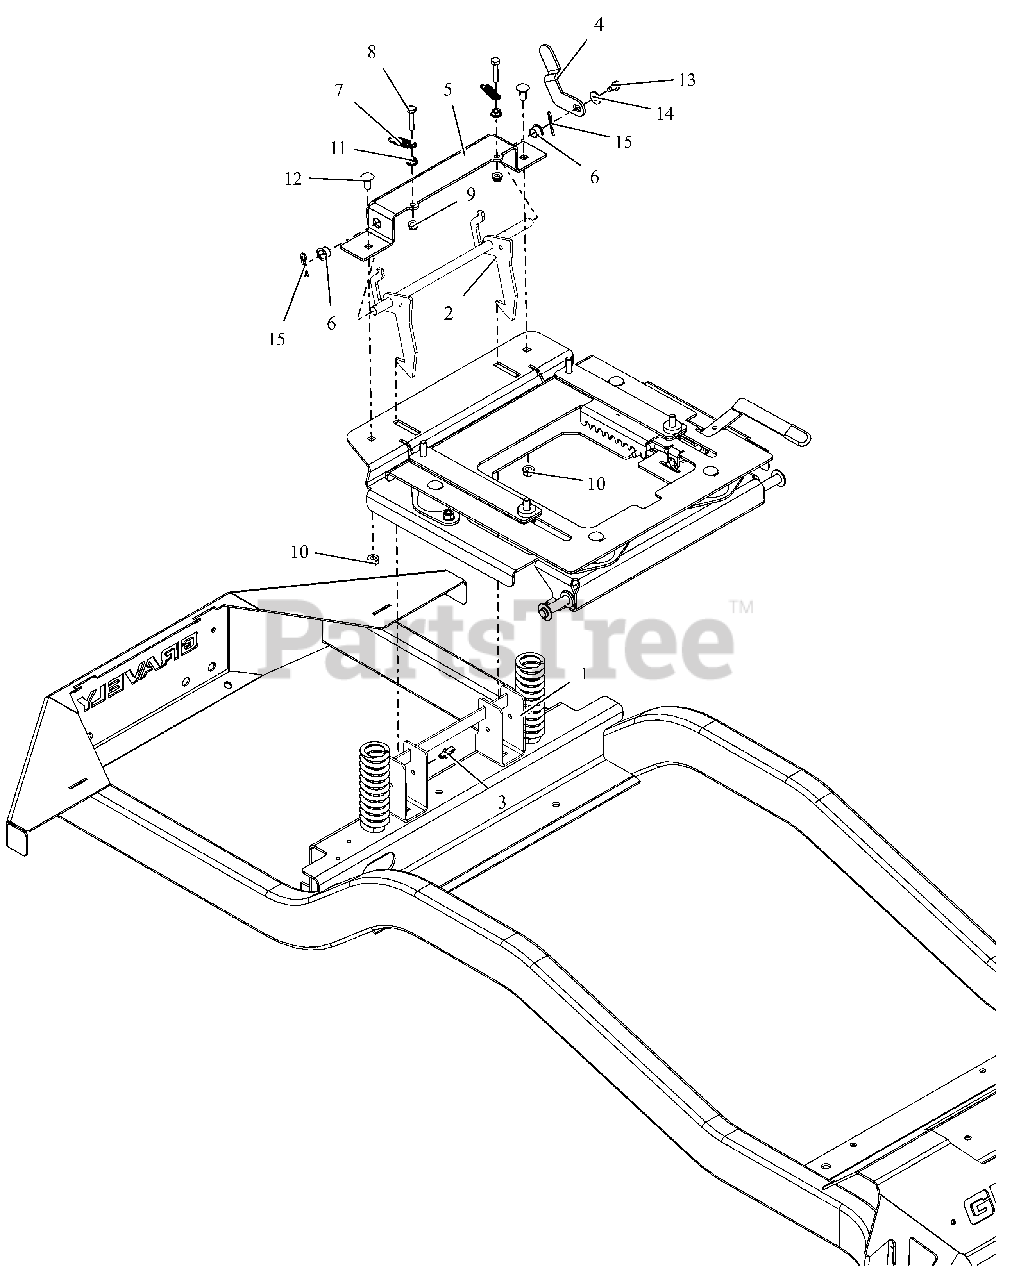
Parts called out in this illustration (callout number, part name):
1	WLDMT, LATCH RECEIVER
2	WLDMT, SEAT
3	ROUTING CLIP (1/2" ID)
4	LEVER, SEAT
5	BRKT, SEAT
6	BUSHING, POLYLINER-.50 SPLIT
7	SG-TENS .063X.44X1.56
8	BLT, HEX .25-20X1.25 G5 ZCC
9	NUT,NYL-FLG .25-20 GF ZCC
10	NUT,LK-CTR-FLG .31-18 GF ZCC
11	NUT-SPNLK-FLG .25-20 ZC120
12	BLT,RHSN .31-18X.75 G5 ZCC
13	SCR-TAP .25-20X.50 HWH ZCC
14	WSHR, FLT .312X.734X.065 ZCC
15	PIN-HAIR INT .08X.38X1.42 YWZC
